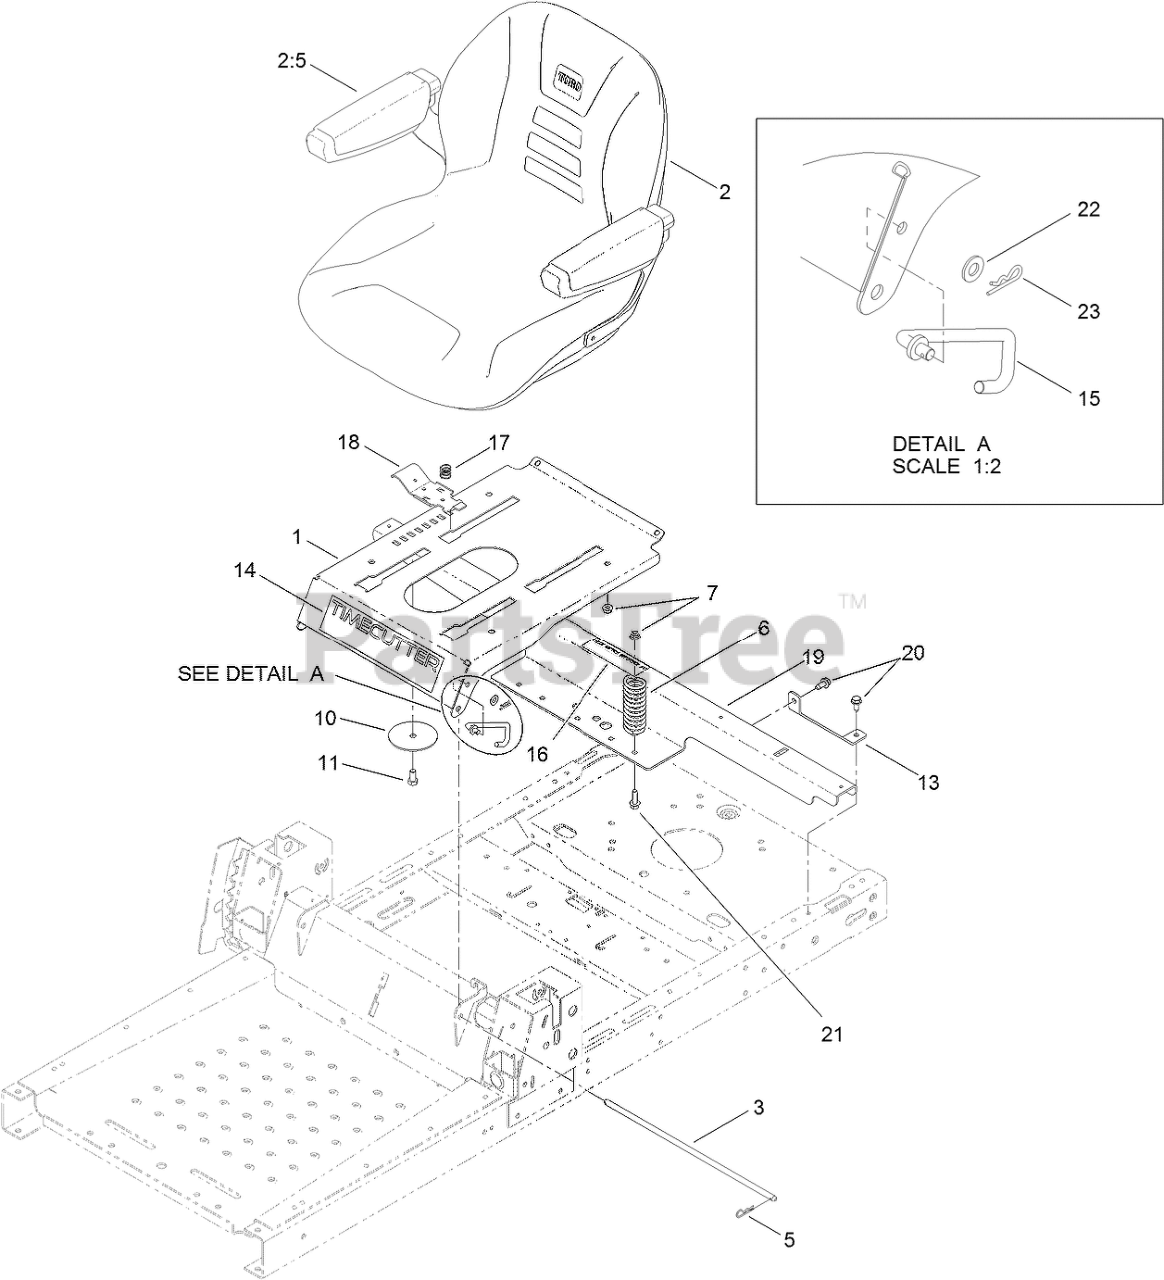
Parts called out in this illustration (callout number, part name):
1	PAN-SEAT
2	18 INCH SEAT ASM
2:5	ARMREST KIT
3	ROD-STOP
5	PIN-COTTER
6	SPRING-COMPRESSION
7	NUT-HF, NI
10	WASHER-SEAT
11	SCREW-HH
13	SUPPORT-TANK, REAR
14	DECAL-TIMECUTTER
15	STOP-SEAT
16	DECAL-SERVICE, CE
17	SPRING-COMPRESSION
18	LATCH-SEAT
19	SUPPORT-POD
20	SCREW-HWHTF
21	SCREW-HHF
22	WASHER-PLAIN
23	PIN-COTTER
